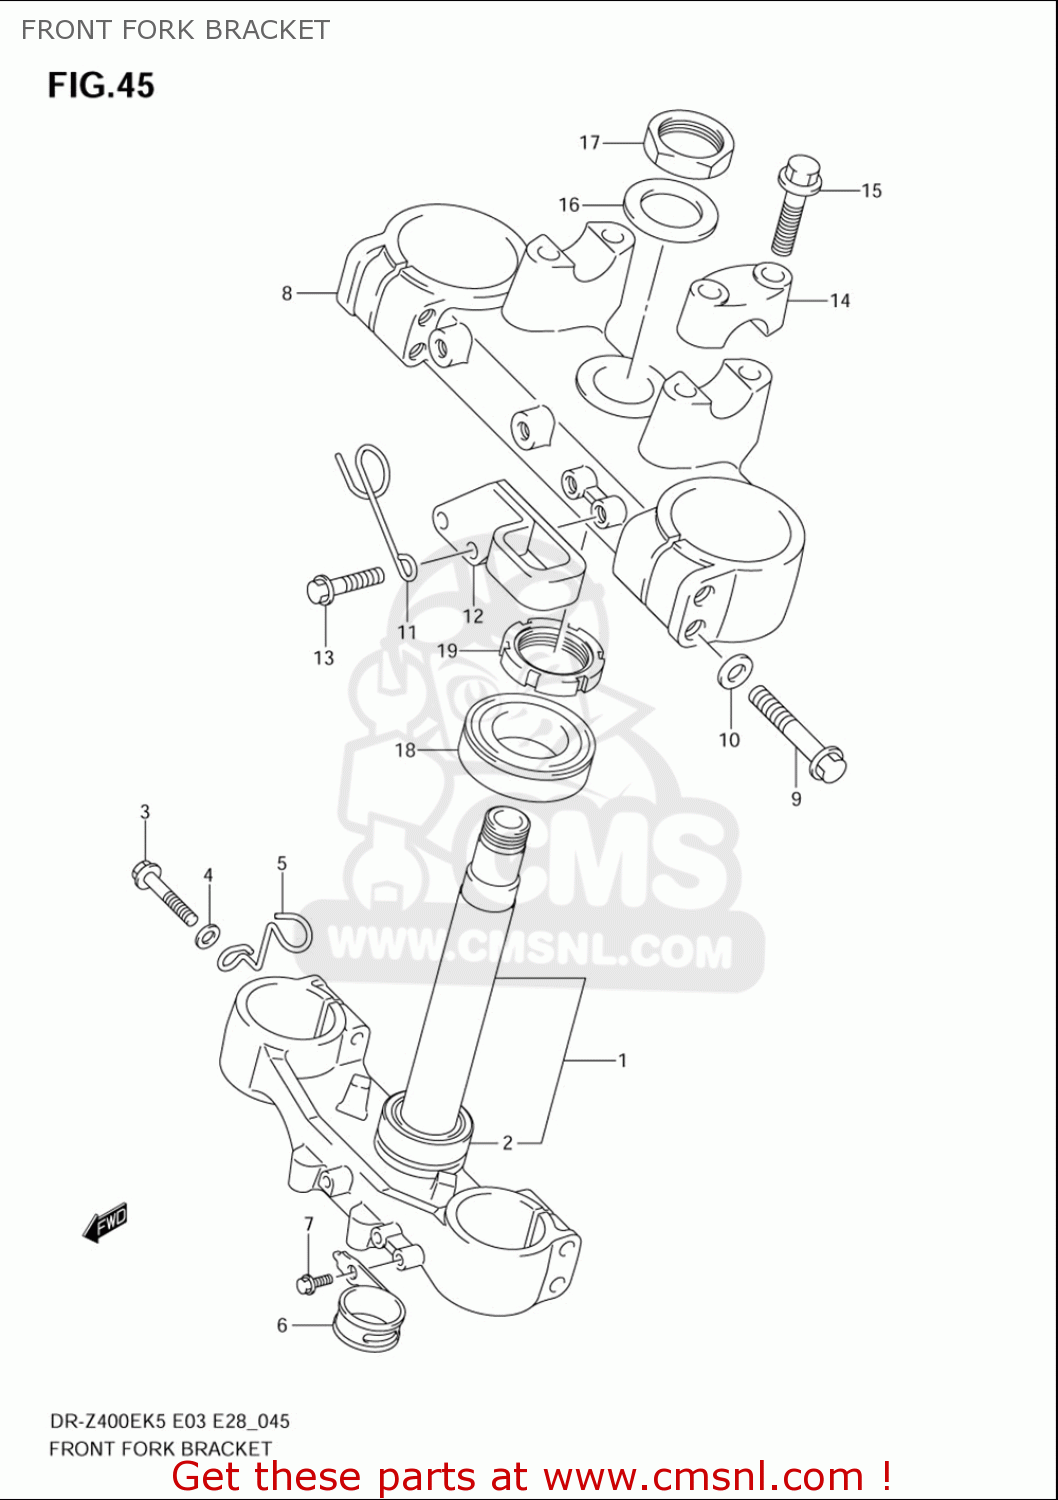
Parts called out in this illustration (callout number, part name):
1	BRACKET,FR FORK UNDER
2	BEARING(30X52X16)
3	BOLT
4	WASHER
5	GUIDE,SPEEDOMETER CABLE
6	GUIDE,CABLE
7	BOLT,PROTECTOR(6X10)
8	BRACKET,FR FORK UPR
9	BOLT
10	WASHER
11	GUIDE,CLUTCH CABLE
12	GUIDE,HOSE
13	BOLT
14	HOLDER,HANDLE
15	BOLT,HANDLE HOLDER(8X35)
16	WASHER,STEM HEAD
17	NUT,STEM HEAD
18	BEARING(30X52X16)
19	NUT,STEERING
